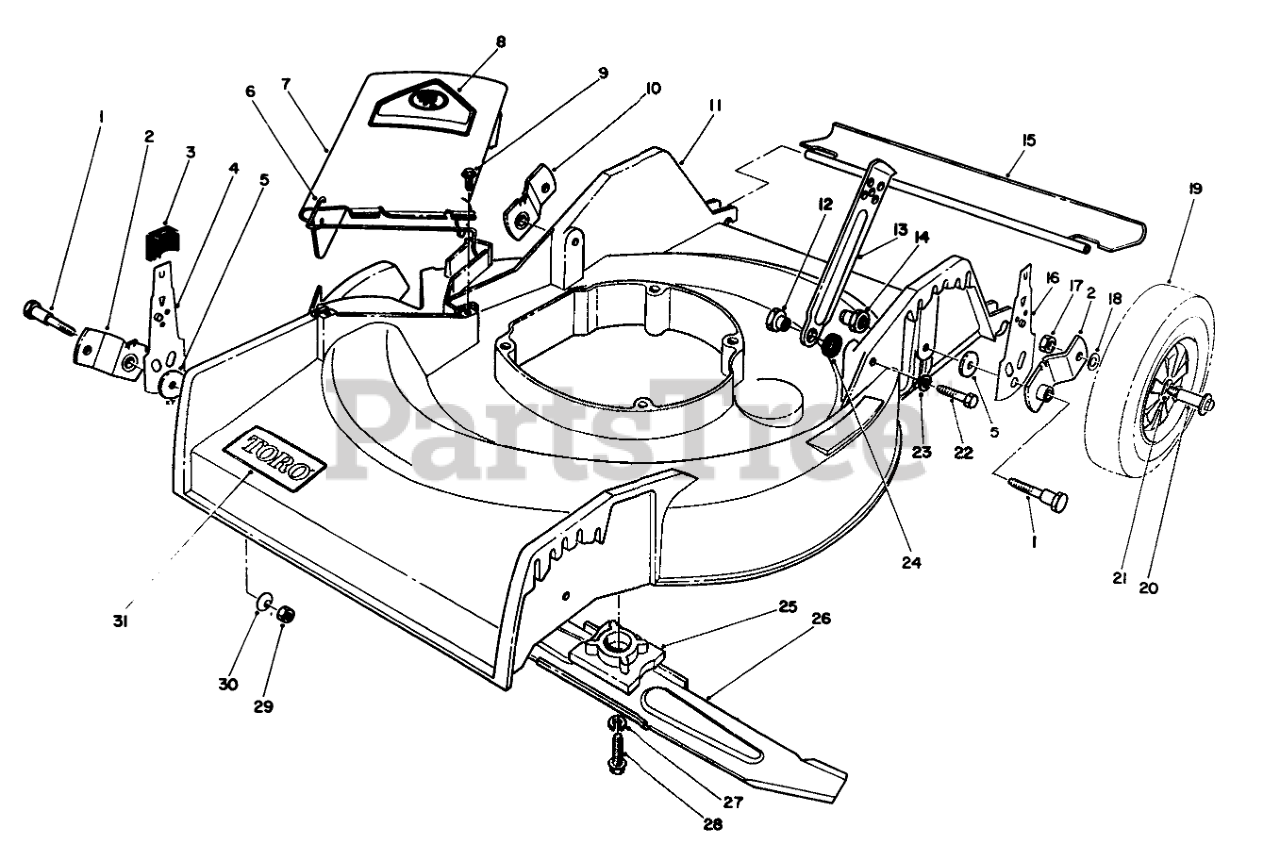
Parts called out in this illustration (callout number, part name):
1	5/16-18 PIVOT SCREW
2	Pivot Arm
3	KNOB-ARM
4	RH FRONT SPRING ARM ASM
5	PIVOT WASHER
6	SPRING HINGE
7	Deflector Assembly (Incl. Ref. #6 & 8)
8	DECAL-DANGER
9	SCREW-HWH
10	Pivot Arm
11	HOUSING W/ DECAL
12	HANDLE PIVOT NUT
13	HANDLE LATCH
14	HANDLE PIVOT NUT
15	SHIELD - TRAILING
16	REAR SPRING ARM ASM
17	Nut
18	WASHER
19	Wheel & Tire Assembly (Incl. Ref. #21)
20	BOLT-WHEEL
21	BUSHING
22	SCREW-HH
23	WASHER-LOCK
24	SPACER
25	BLADE RETAINER
26	Blade
27	WASHER-LOCK
28	SCREW-HH
29	NUT-LOCK, NI
30	WASHER-BELLEVILLE
31	DECAL
